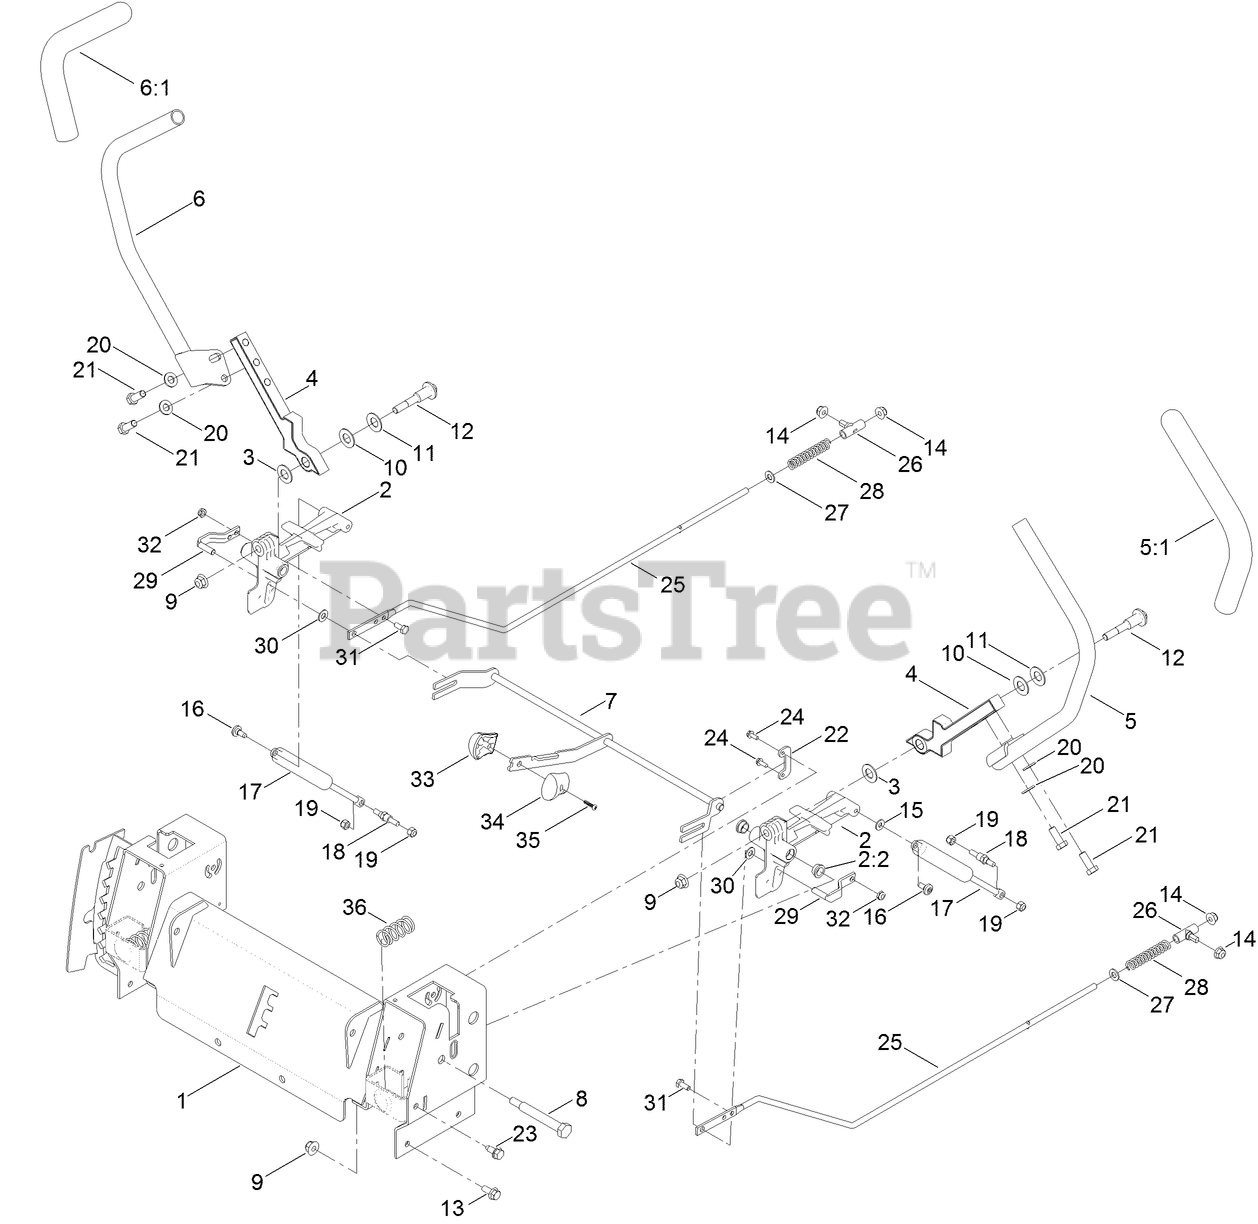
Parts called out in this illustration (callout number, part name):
1	CONTROL BOX ASM
2	ACTUATOR ARM ASM
2:2	BUSHING-FLANGE
3	WASHER-NYLON
5	HANDLE-CONTROL, LH
6	HANDLE-CONTROL, RH
8	BOLT-PIVOT
9	NUT-HF, NI
10	WASHER
11	WASHER-BELLEVILLE
12	BOLT-PIVOT
13	SCREW-HHF
14	NUT-HF, NI
15	WASHER
16	SCREW-SHOULDER
17	DAMPER
18	STUD-DAMPER
19	NUT-LOCK, NI
20	WASHER-FLAT
21	SCREW-HH
22	RETAINER
23	SCREW-HWHTF
24	SCREW-TAPTITE
25	ROD-HYDRO
26	MOUNT-ROD, HYDRO
27	WASHER-PLAIN
28	SPRING-RETURN, NEUTRAL
30	SPACER-NYLON
31	SCREW-HH
32	NUT-LOCK, NI
35	SCREW-PPH
36	SPRING-RETURN
